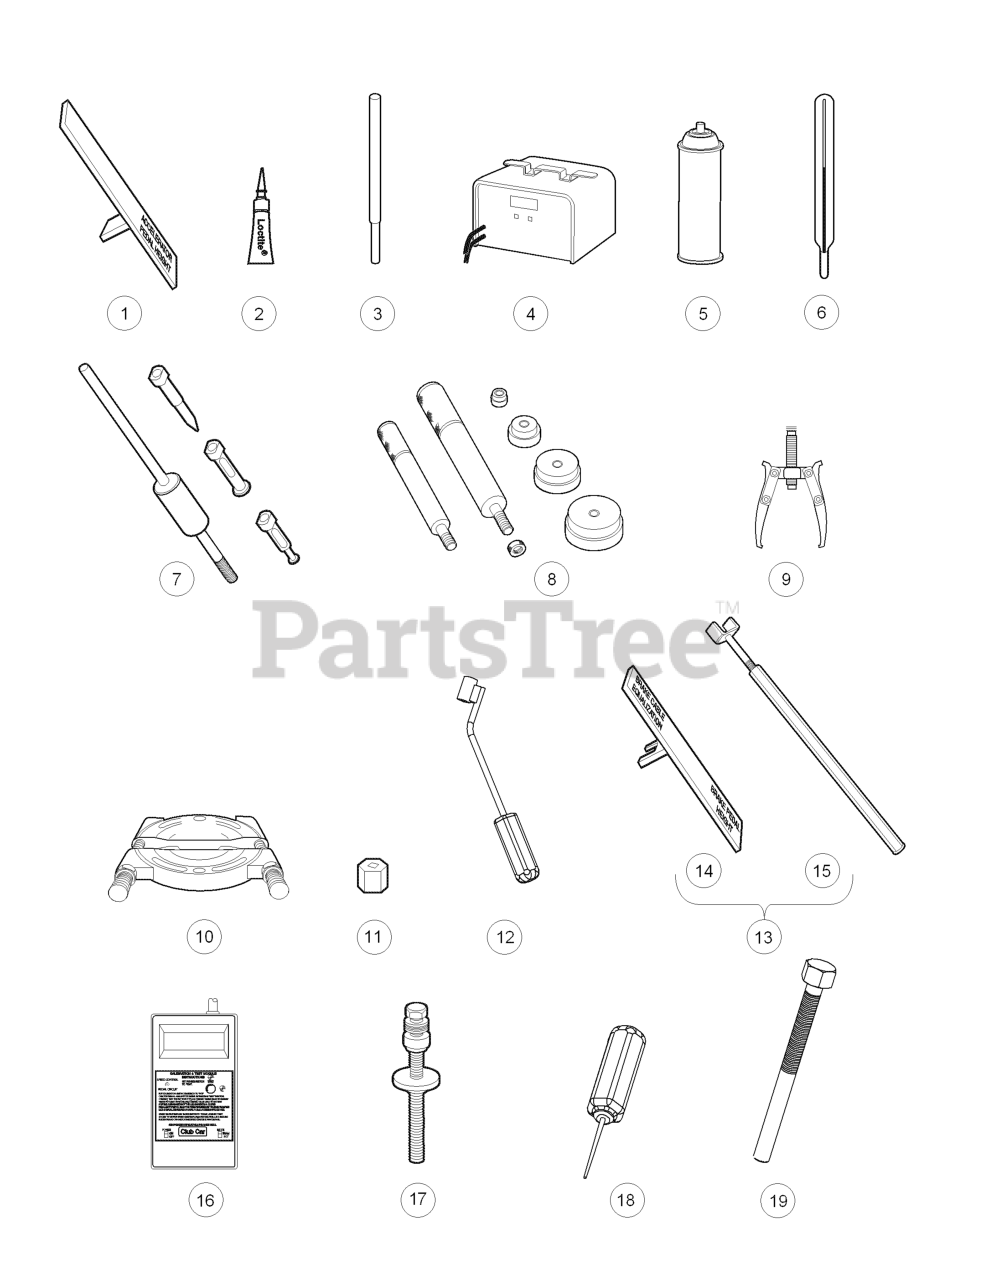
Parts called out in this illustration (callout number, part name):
1	TOOL, ACCEL. PEDAL ADJUSTMENT
2	GUIDE RING ADHESIVE 3 GRAMS
4	BATTERY DISCHARGE UNIT 36/48V
5	BATTERY TERMINAL PROTECT SPRAY
6	BATTERY THERMOMETER
7	BEAR & OIL SEAL REMOVER ASM
8	BEARING DRIVER SET
9	BEARING PULLER
10	BEARING PULLER WEDGE ATTACH.
11	BRAKE ADJUSMENT SOCKET TOOL
12	BRAKE CABLE RELEASE TOOL
13	Brake Pedal Adjustment Tool Kit
14	Brake Pedal Adjustment Tool
15	Brake Pedal Tension Tool
16	CALIBRATION & TEST MODULE
17	CAM INSTALLATION TOOL
18	CHARGER BEZEL TOOL
19	TOOL, REMOVAL, CLUTCH, GAS/DSL
